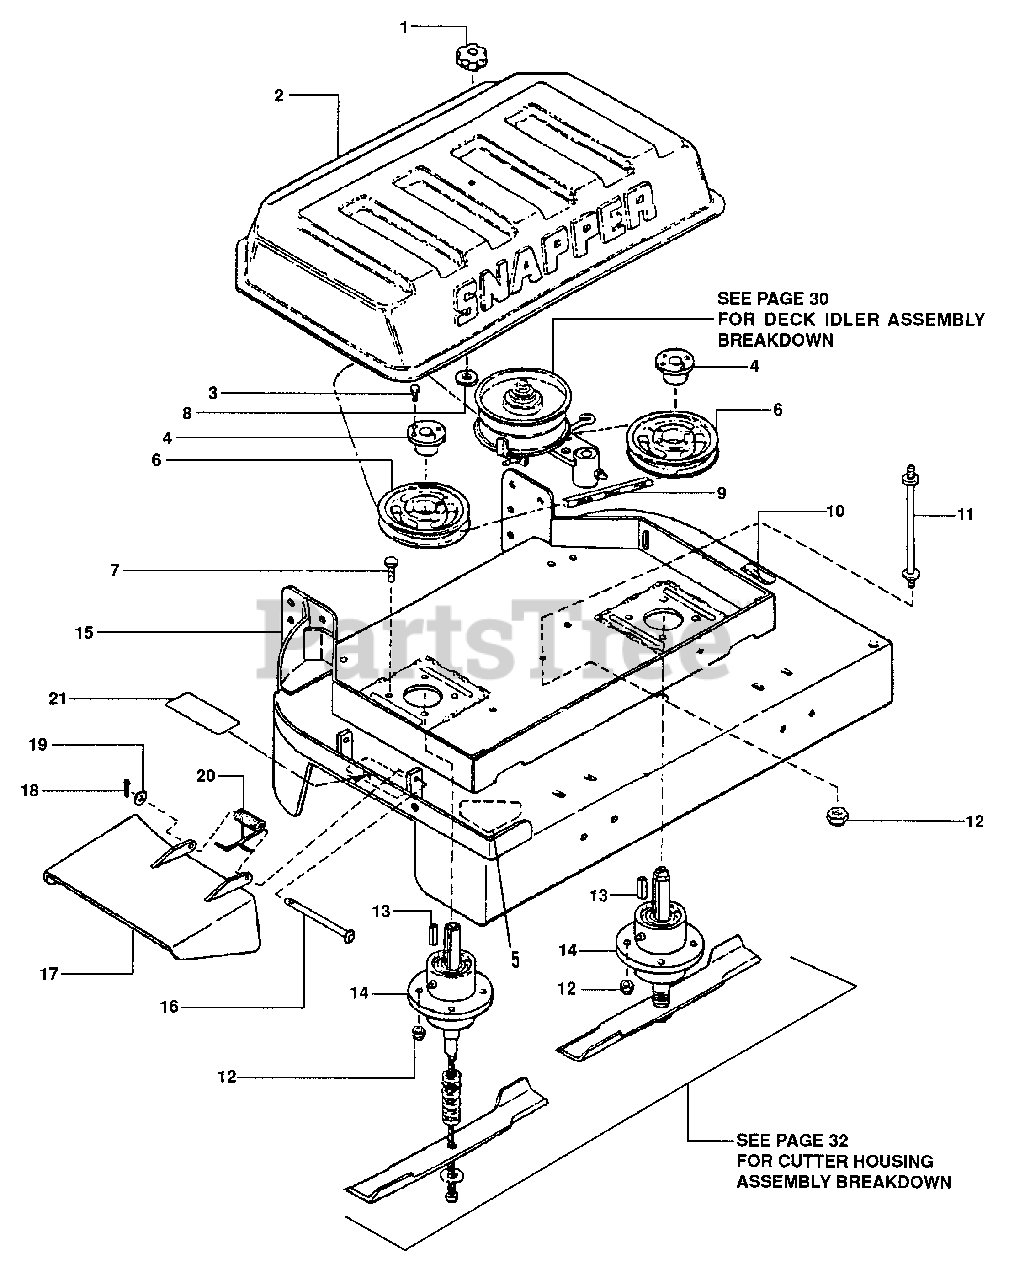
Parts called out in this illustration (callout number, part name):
1	KNOB, Hood
3	BOLT, 1/4-20 X 7/8" Hex Head Cap
4	BUSHING, Taperlock
5	DECAL, Danger
6	PULLEY, Cutter Blade Drive
7	SCREW, 3/8-16 X 1 1/4" Hex Head Cap
8	WASHER, 13/32" I.D. X 1-1/2" O.D.
9	BELT, 36" Deck
10	DECAL, Caution
11	STUD, Hood Mount
12	NUT, 3/8-16 Hex, Nyloc
13	KEY, Spindle, 1/4 X 1/4 X 2 1/2"
14	ASSEMBLY, Cutter Housing
15	WELDMENT, 36" Deck
16	ROD, Chute Pivot
17	DEFLECTOR, 36" Chute
18	PIN, 3/32 X 1" Cotter
19	WASHER, 5/16 Flat
20	SPRING, Chute
21	DECAL, Caution
